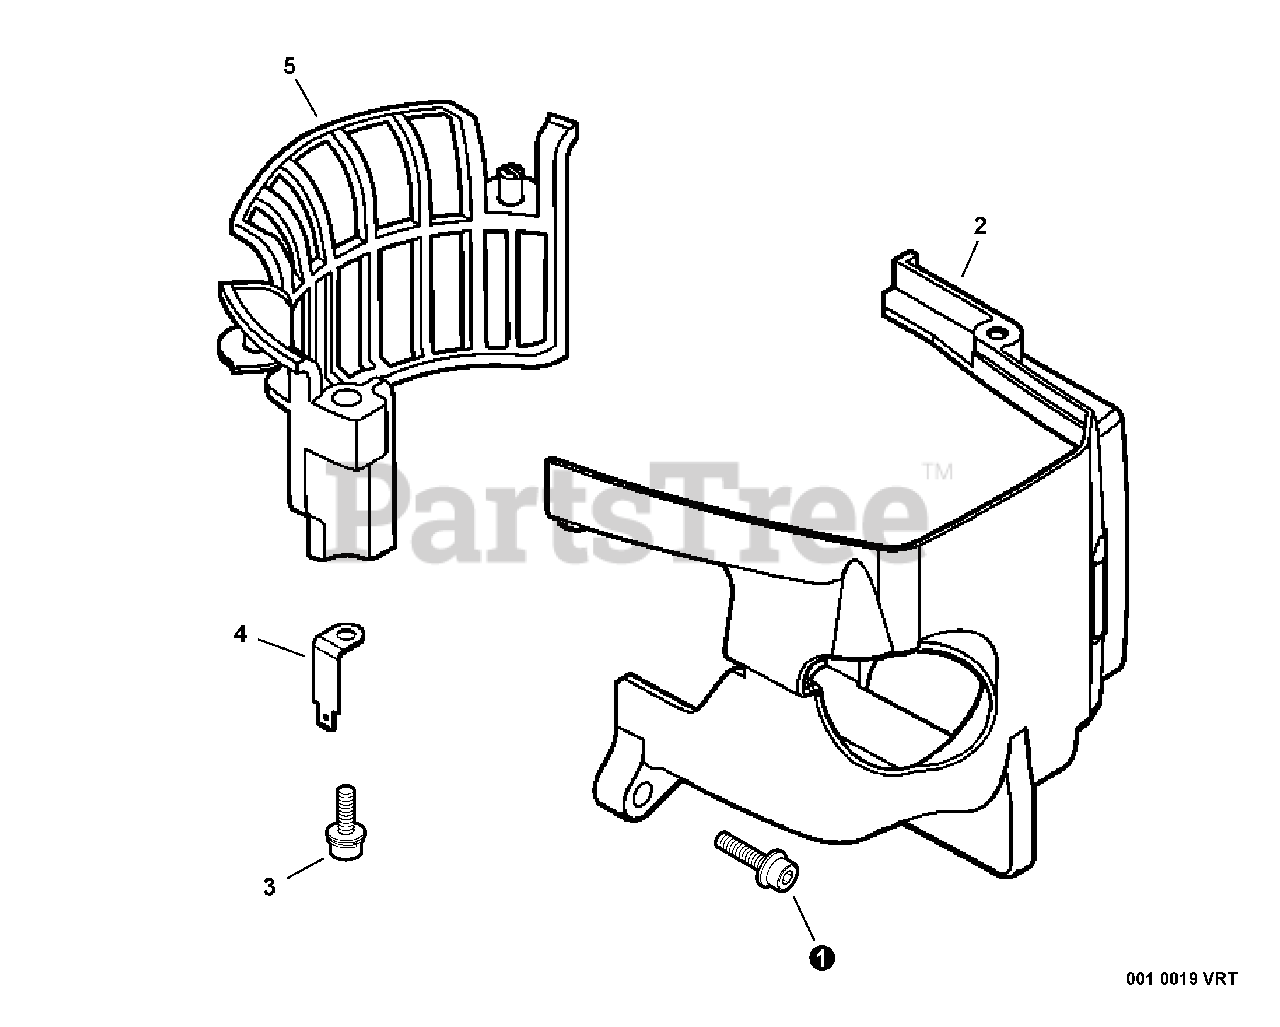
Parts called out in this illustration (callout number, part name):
1	BOLT 5×16
2	COVER, ENGINE
3	BOLT 5×16
4	CONNECTOR
5	SHIELD, DEBRIS
